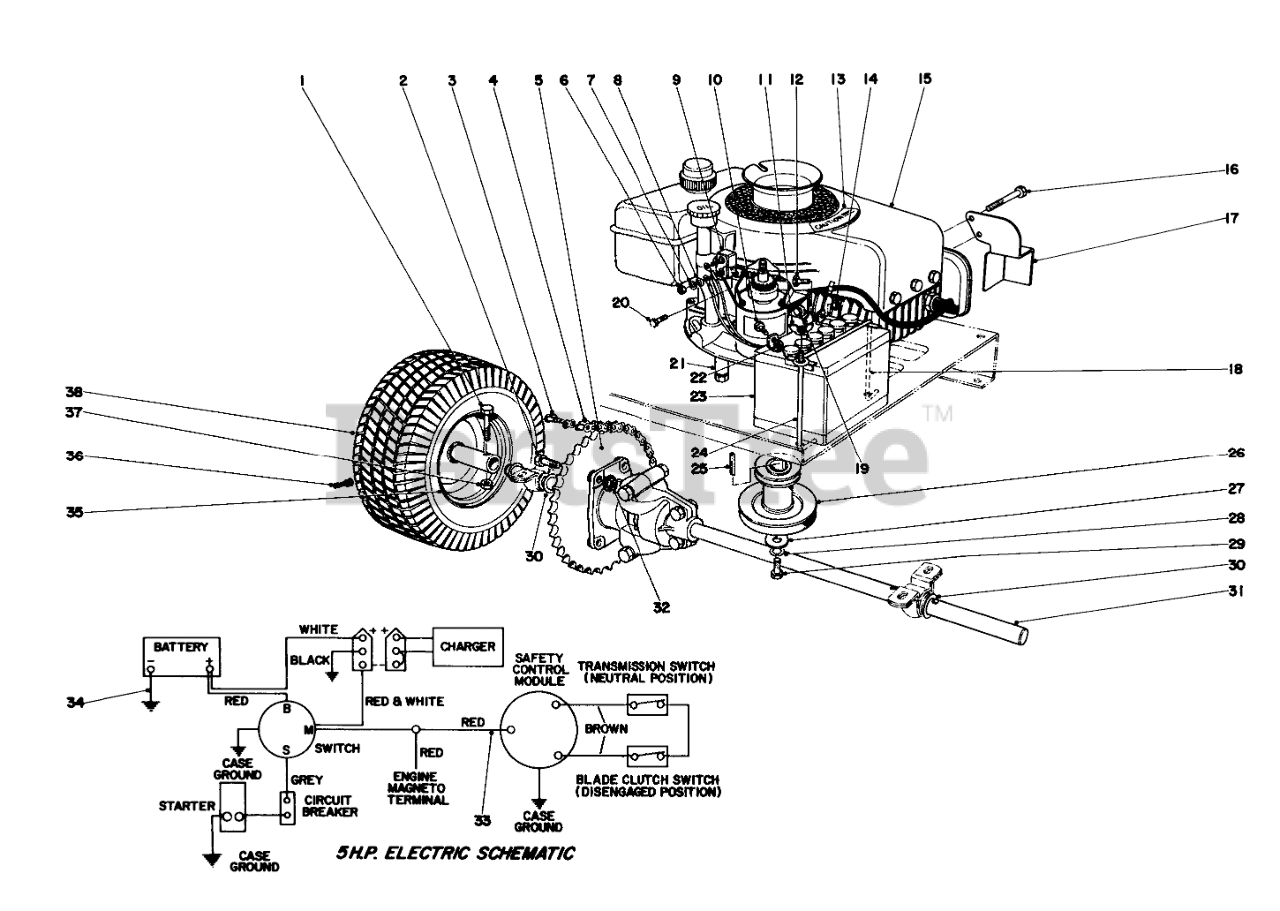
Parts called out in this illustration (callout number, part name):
1	SCREW-HH
2	SCREW-HH
3	LINK-CONNECTING
4	Chain Roller
5	Sprocket
6	NUT-HEX
7	WASHER-LOCK/SP
8	WASHER-FLAT
9	Breaker Circuit
10	SCREW-HH
11	NUT-WING SPECL
12	SCREW-HH
13	Decal
14	NUT-HEX
15	Engine
16	SCREW-HH
17	Deflector
18	Battery Clamp
19	SCREW
20	Screw
21	Extension Oil Drain
22	NUT-HEX
23	Battery
24	ROD-SUPPORT, BATTERY
26	Pulley
27	Washer
28	WASHER-LOCK
29	SCREW-HH
30	WASHER
31	Differential
32	NUT-LOCK, CONE
33	Wiring Harness
34	ENG-GROUND WIRE ASM
36	STEM-VALVE
37	NUT-LOCK, CONE
38	Tire
